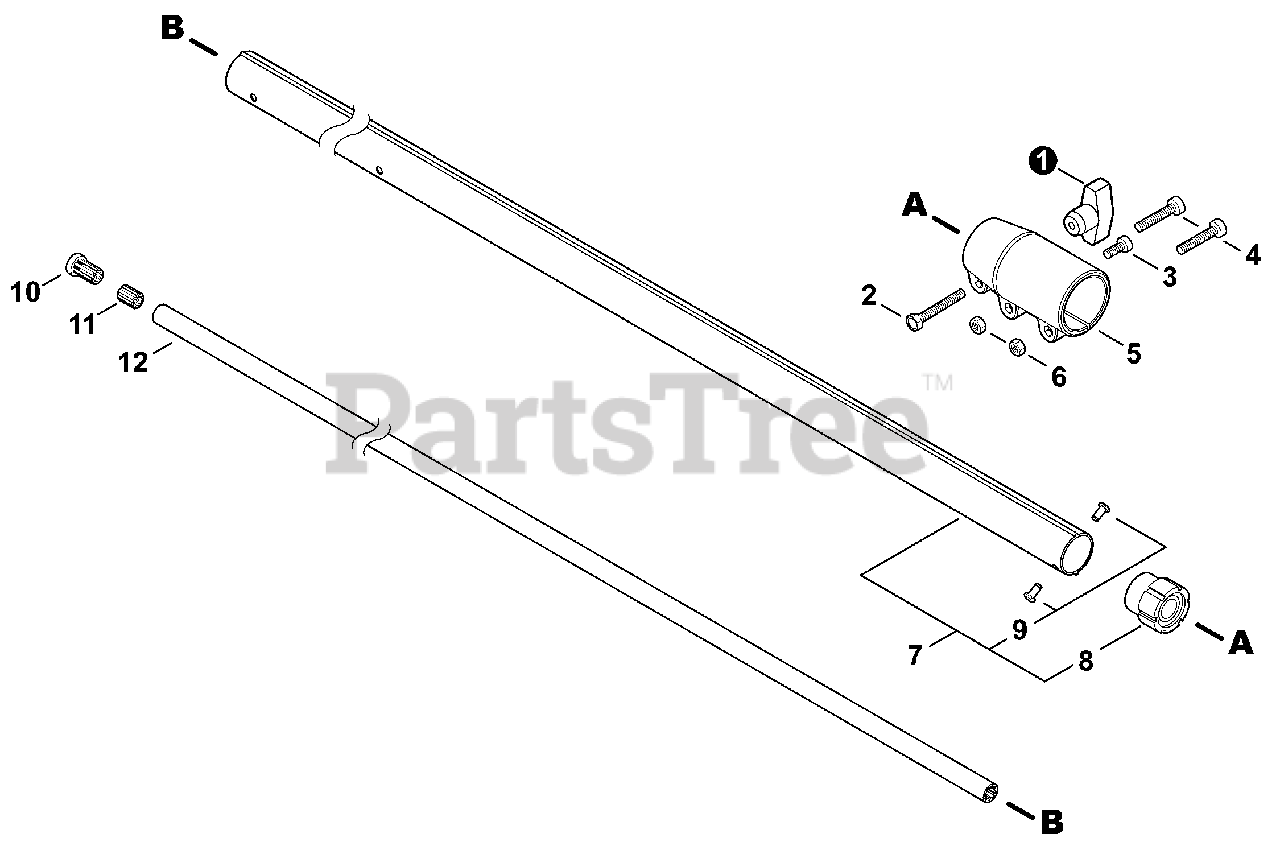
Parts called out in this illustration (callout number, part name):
1	THUMBSCREW
2	BOLT 6x25
3	BOLT 5x12
4	BOLT 5x20 HSH
5	COUPLING
7	MAIN PIPE ASSY - BLACK
8	HOLDER ASSY, BEARING
10	SOCKET - OUTER
11	SOCKET - INNER
12	DRIVESHAFT - UPPER
